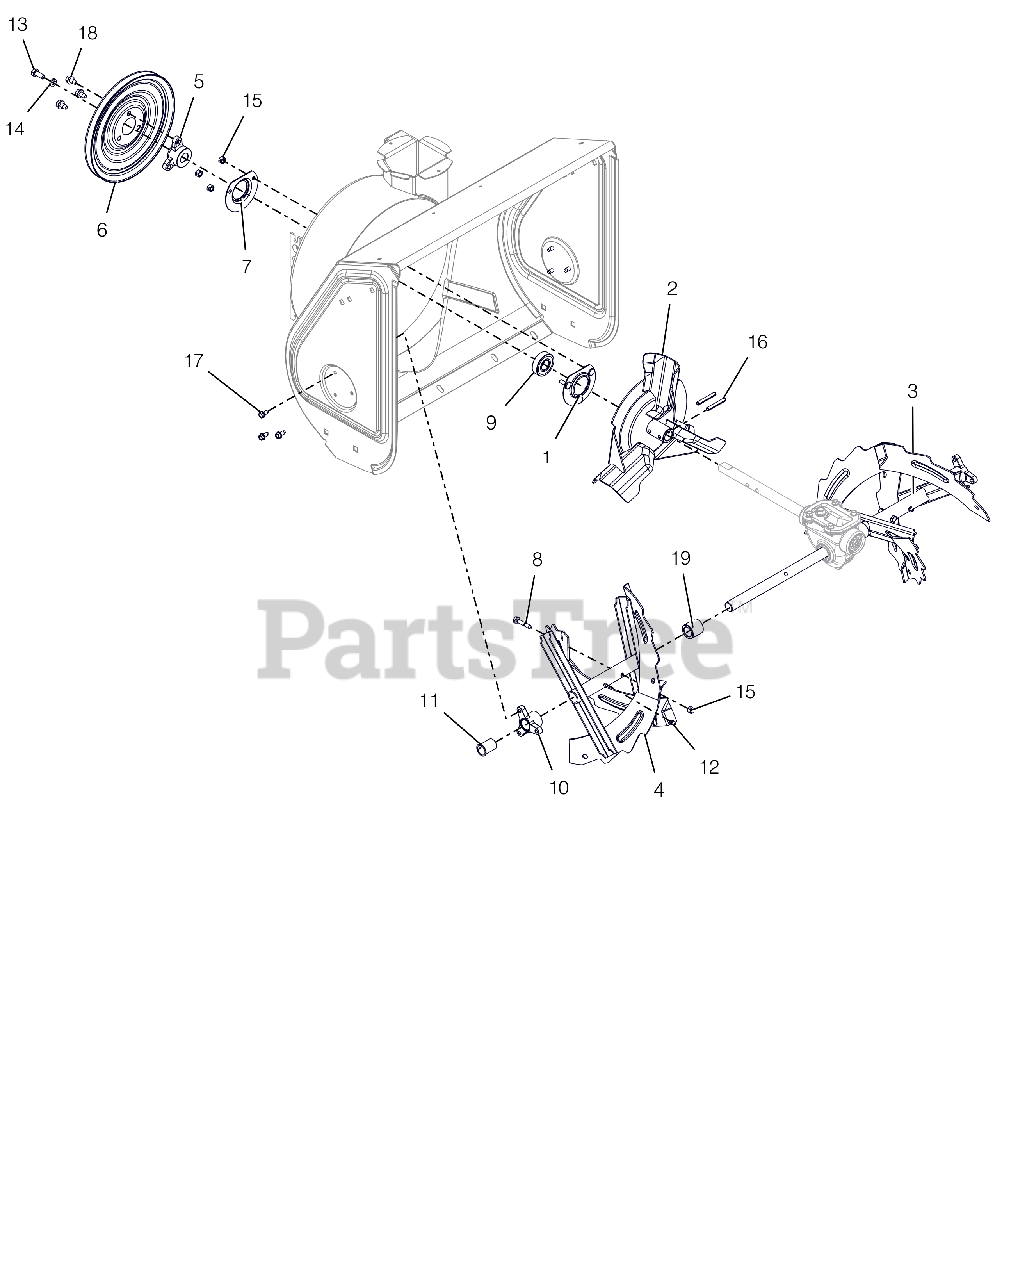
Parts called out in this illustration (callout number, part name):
1	BEARING FLANGE
2	IMPELLER, COMPACT 12" 3-BLADE
3	AUGER, LH 20", BLK SERR W/ZERK
4	AUGER, 20" RH, BLK SERR W/ZERK
5	PULLEY HUB, BOLT-ON D-BORE .75
6	PULLEY,SPIN FORM SINGLE GROOVE
7	BEARING FLANGE
8	SHEAR BOLT
9	BRG-BALL .750X1.750X.50
10	BUSHING, RAKE SHAFT .75"
11	BSHG-FLG SPLIT NYLINER .75"ID
12	ZERK,FITTING .25X.125 DRIVE IN
13	BLT-HEX .31-24X.75 YWZC GR5
14	WSHR-LK .312X.097 HVY YWZC
15	@NUT-LK-CTR .25-20 YWZC
16	PIN-ROLL .250X1.75
17	SCR-TAP .25-20X.50 HWH TR YWZ
18	@SCR-TAP .31-18X.50 HWH TR YWZ
19	BSHG-SLV .75X1.12X1.062 NYL BK
